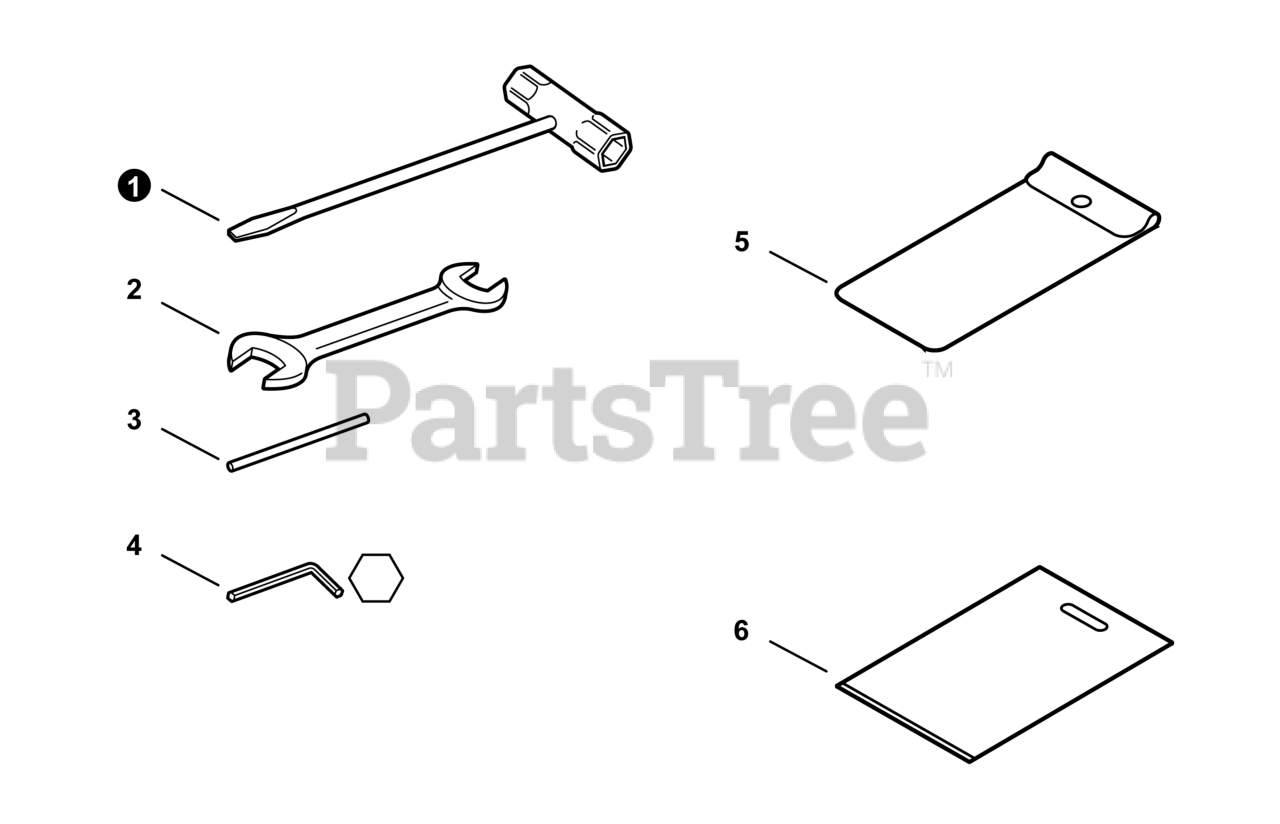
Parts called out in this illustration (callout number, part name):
1	T-WRENCH 17x19 L200
2	SPANNER 8x10
3	TOOL, LOCKING 5x120 MM
4	WRENCH, ALLEN 4 MM
5	BAG, TOOL
6	CASE, TOOL
